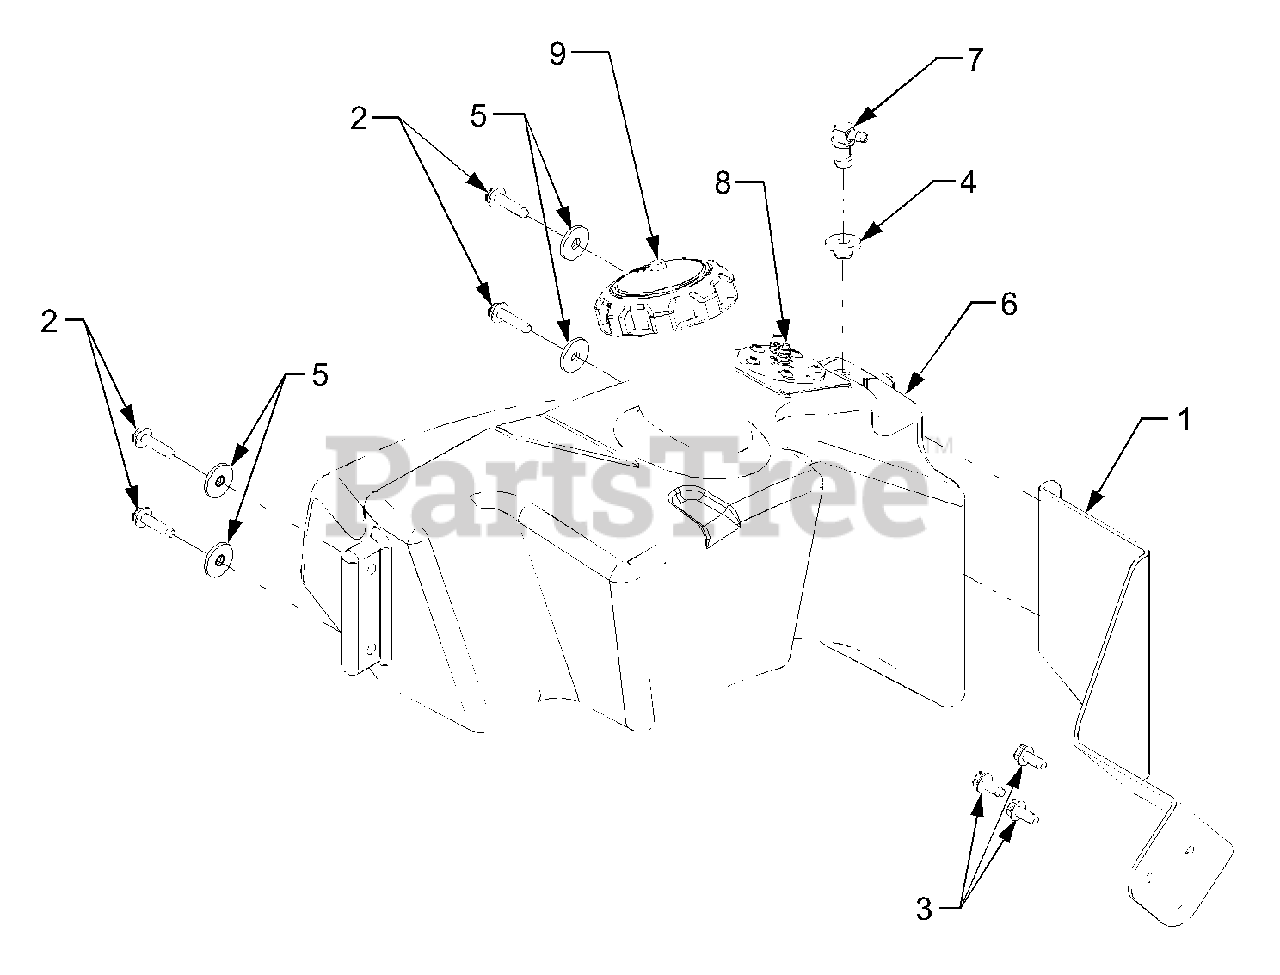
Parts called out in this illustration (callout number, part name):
1	Bracket, Front Tank Mtg
2	Screw, Hex Wash Hd Tapp 5/16-18 x 1.25
3	Screw, Hex Wash Hd Tapp 5/16-18 x .75
4	Bushing, Rubber
5	Washer, Flat, .344 x 1.125 x .12
6	Tank, Fuel
7	Fitting, Fuel Return
8	Sensor, Fuel Level
9	Cap, Fuel - Diesel
